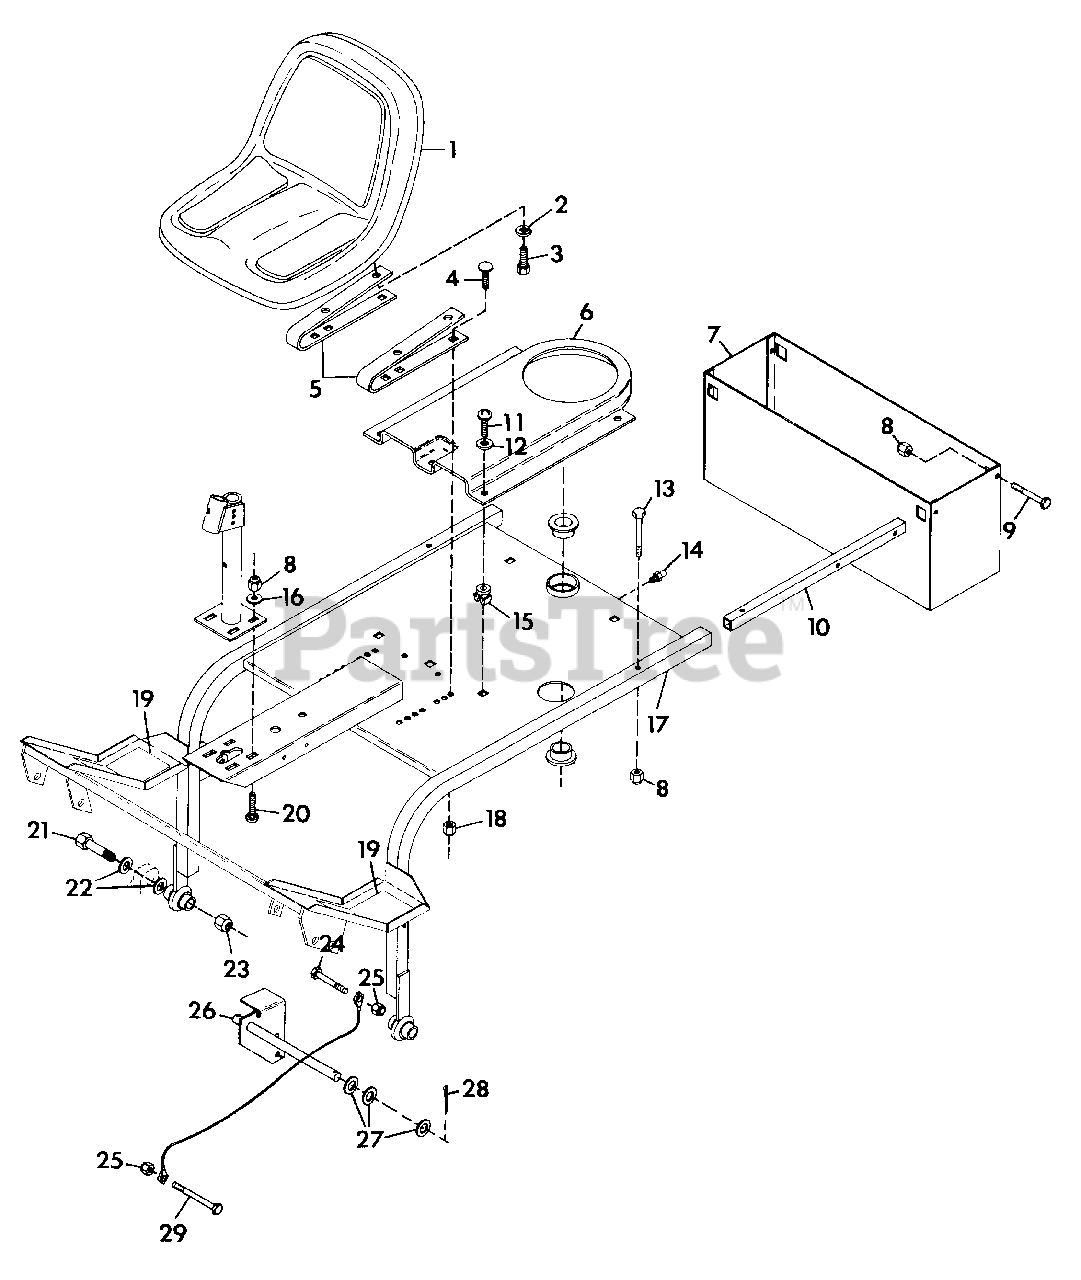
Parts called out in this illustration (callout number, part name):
1	SEAT, HIGH BACK
2	WASHER, LOCK 5/16
3	BOLT, HEX 5/16-18X.75
4	BOLT, CARRIAGE 5/16-18X1.00
5	SPRING, SEAT
6	COVER, CHAIN
7	WELDMENT, WEIGHT BOX
8	NUT, LOCK 3/8-16
9	BOLT, HEX 3/8-16X2.25
10	TUBE, SUPPORT
11	SCREW, TAPPING 1/4-20X.625 P/HD
12	WASHER, FLAT .281X.625X.065
13	BOLT, HEX 3/8-16X2.75
14	FITTING, LUBE 1/4-28
15	GROMMET, PLASTIC
16	WASHER, FLAT .406X.812X.065
17	WELDMENT, FRAME
18	NUT, LOCK 5/16-18
19	COVER, LARGE FOOTBOARD
20	BOLT, 3/8-16X1.00 RD HD SQ NK
21	BOLT, HEX 3/4-10X3.75
22	WASHER, FLAT .812X1.469X.130
23	NUT, LOCK 3/4-10
24	BOLT, HEX 5/16-24X2.25
25	NUT, LOCK 5/16-24
26	WELDMENT, LIFT BRACKET
27	WASHER, FLAT .656X1.250X.100
28	PIN, COTTER .125X1.25
29	BOLT, HEX 5/16-24X3.50
NS	DECAL, PRO MASTER-60
NS	DECALS, PRO MASTER
NS	DECAL, GRAVELY LOGO
NS	DECAL, AMERICA
